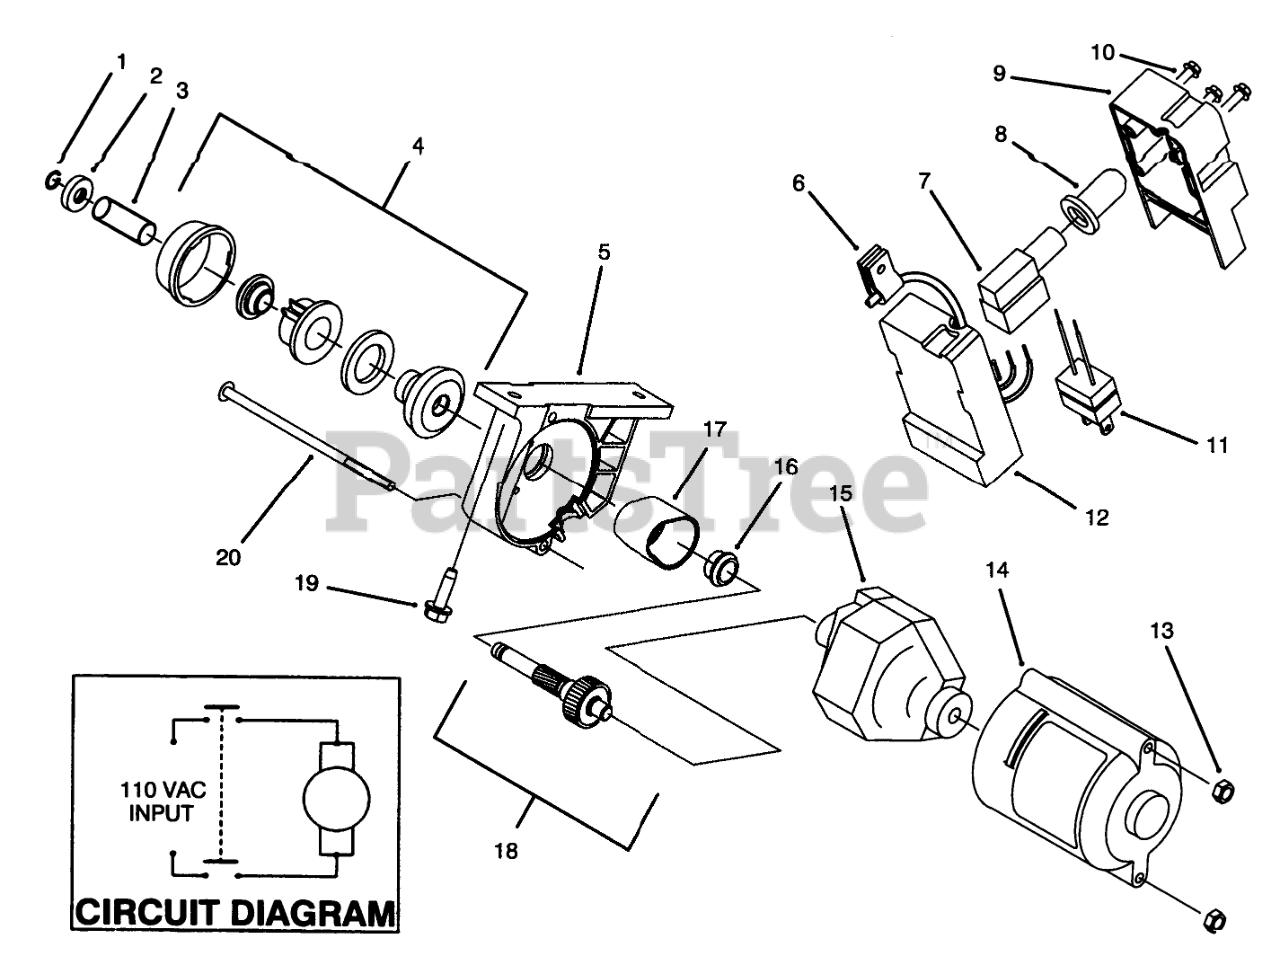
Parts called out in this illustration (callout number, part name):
1	RING-LOCK
2	PINION STOP
3	SPRING
4	Pinion ASM
5	HOUSING
6	CLAMP
7	SWITCH-STARTER
8	BOOT-SWITCH
9	Cap-Switch Housing
10	SCREW-PLASTITE
11	Plug
12	OBS BASE X
13	NUT-LOCK, NI
14	HOUSING - LOWER STARTER
15	STARTER MOTOR ASSEMBLY
16	BUSHING
17	COVER-GEAR
18	Asm-shaft & Gear
19	SCREW
